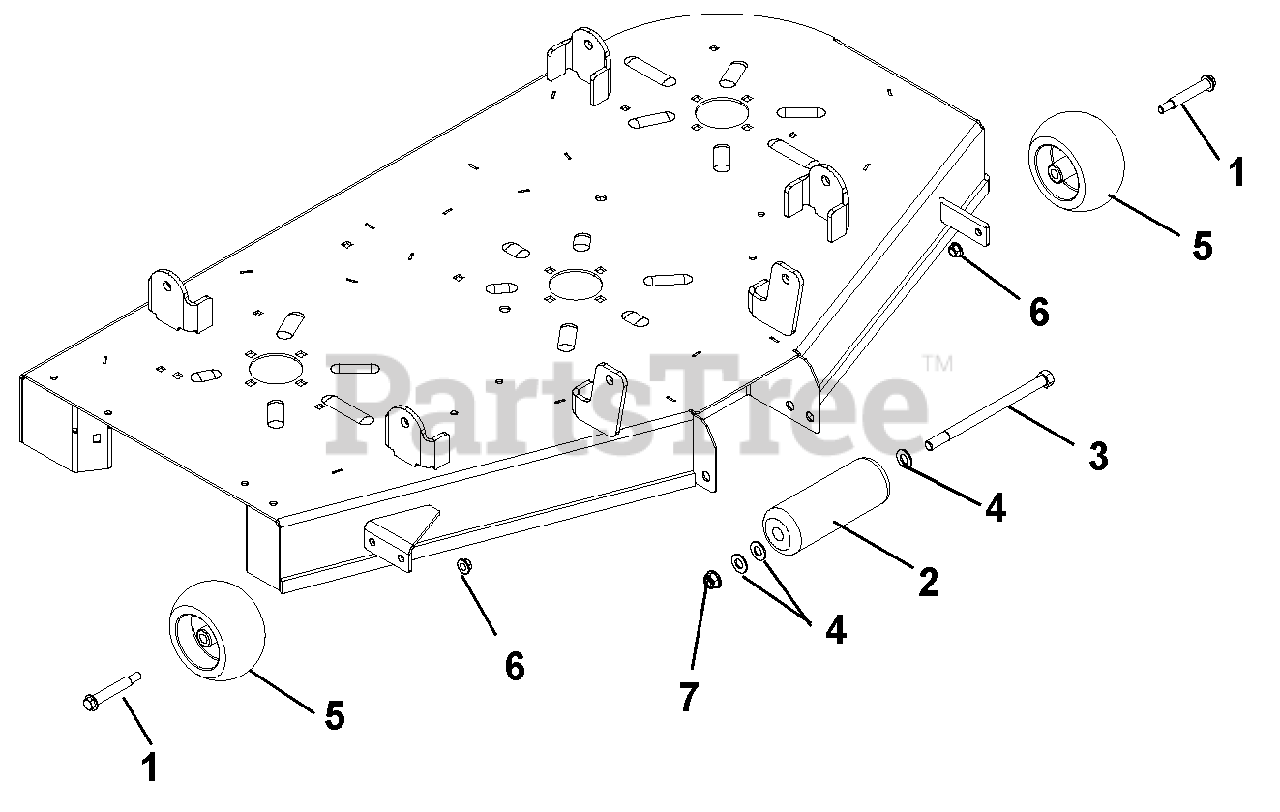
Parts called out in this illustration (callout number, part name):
1	BLT-SHLDR .38-16X2.50 HWH G5
3	@BLT-HEX .50-13X8.00 GR5 YWZC
4	WSHR-FL-NYL .518X1.000X.080
5	ANTI-SCALP WHEEL - 5X OS
6	@NUT-LK-TOP-FLG .38-16 YWZC
7	@NUT-LK-NYL .50-13 YWZC
